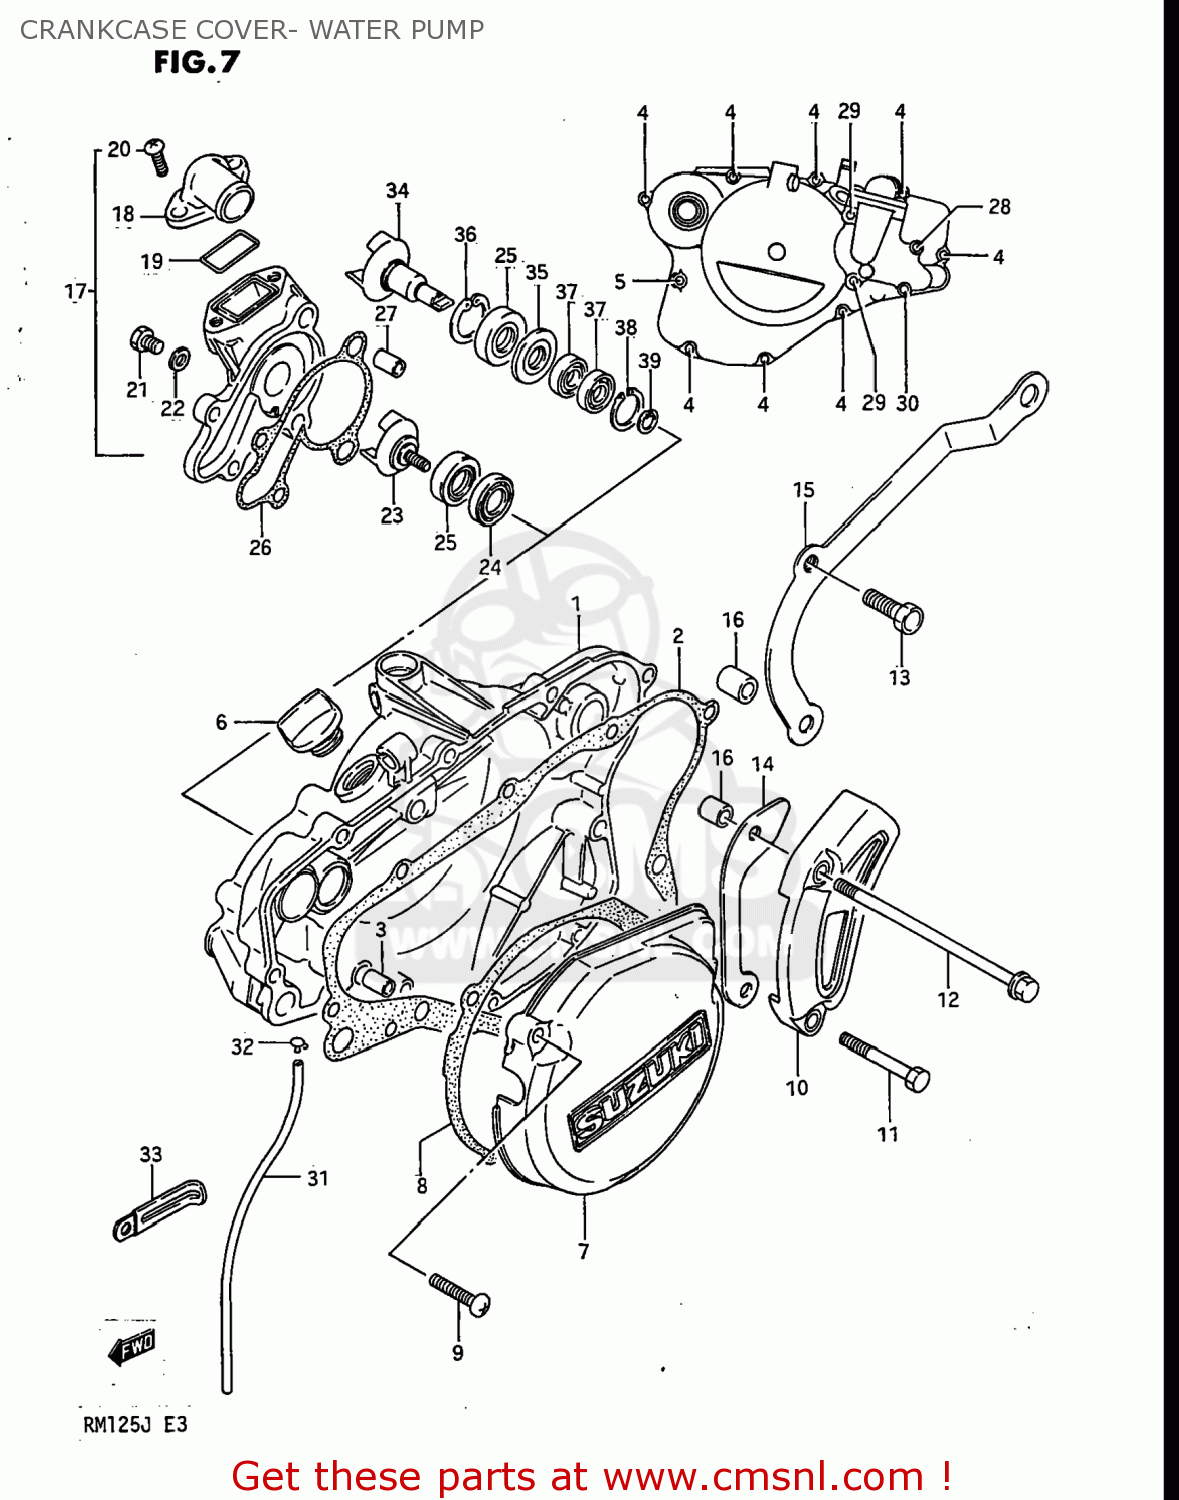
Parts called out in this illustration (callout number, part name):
1	COVER,CLUTCH
2	GASKET,CLUTCH COVER (MCA)
3	PIN
4	SCREW
5	SCREW
6	PLUG SET
7	COVER,MAGNETO
8	GASKET,MAGNETO COVER (MCA)
9	SCREW
10	COVER,SPROCKET
11	BOLT 6X40
12	BOLT(6X105)
13	BOLT
14	PLATE,CHAIN GUIDE
15	PLATE COMP,FRONT CHAIN
16	SPACER(6.5X10.5X12)
17	CASE,WATER PUMP
18	CONNECTOR
19	O RING,WATER PUMP CONNECTOR
20	SCREW
21	BOLT,BLEEDER
22	GASKET (NAS)
23	IMPELLER,WATER PUMP
24	SEAL,OIL(12X24X7)
25	SEAL,OIL(12X24X6.4)
26	GASKET,WATER PUMP CASE
27	PIN
28	SCREW
29	SCREW 6X30
30	SCREW 6X85
31	HOSE
32	CLIP
33	CLAMP
34	IMPELLER,WATER PUMP
35	SEAL,OIL(12X24X3.6)
36	CIRCLIP
37	BEARING
38	CIRCLIP
39	CIRCLIP
